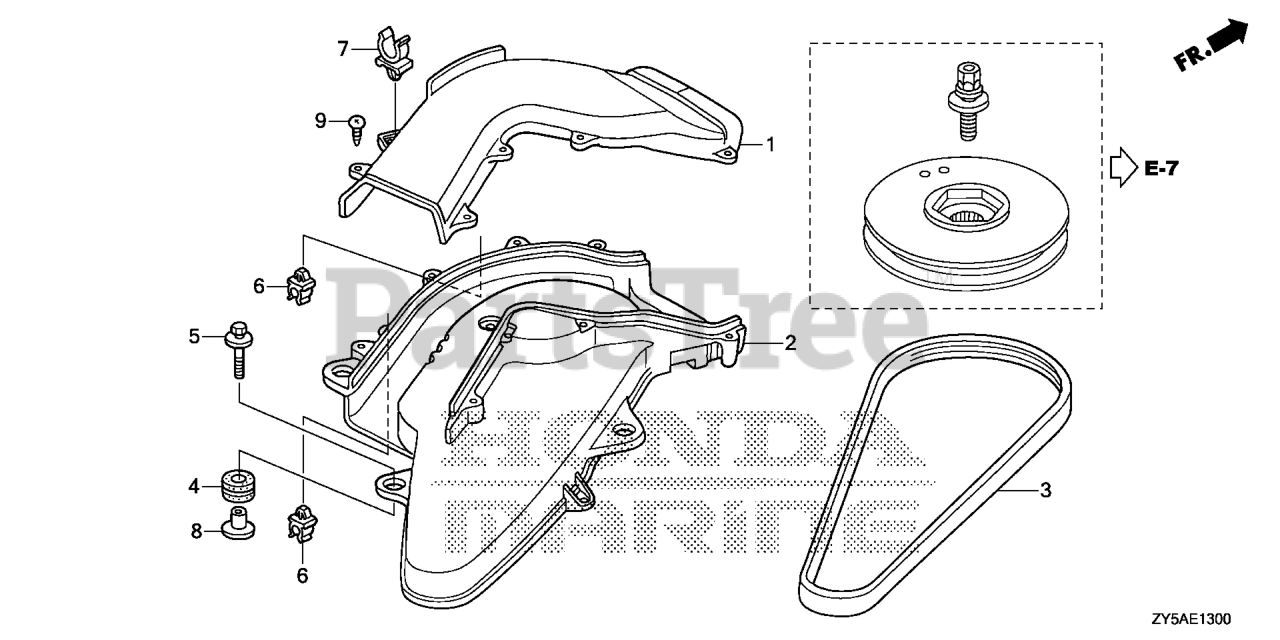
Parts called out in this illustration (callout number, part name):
1	DUCT A, MUFFLER
2	DUCT B, MUFFLER
3	BELT, ALTERNATOR (4PK810)
4	GROMMET, CASE (LOWER)
5	BOLT-WASHER (6X25)
6	CLIP, TUBE (3.5)
7	CLAMP (18.5MM)
8	COLLAR, MODULE IGNITION CONTROL CASE (CDI)
9	SCREW, TAPPING (5X20)
